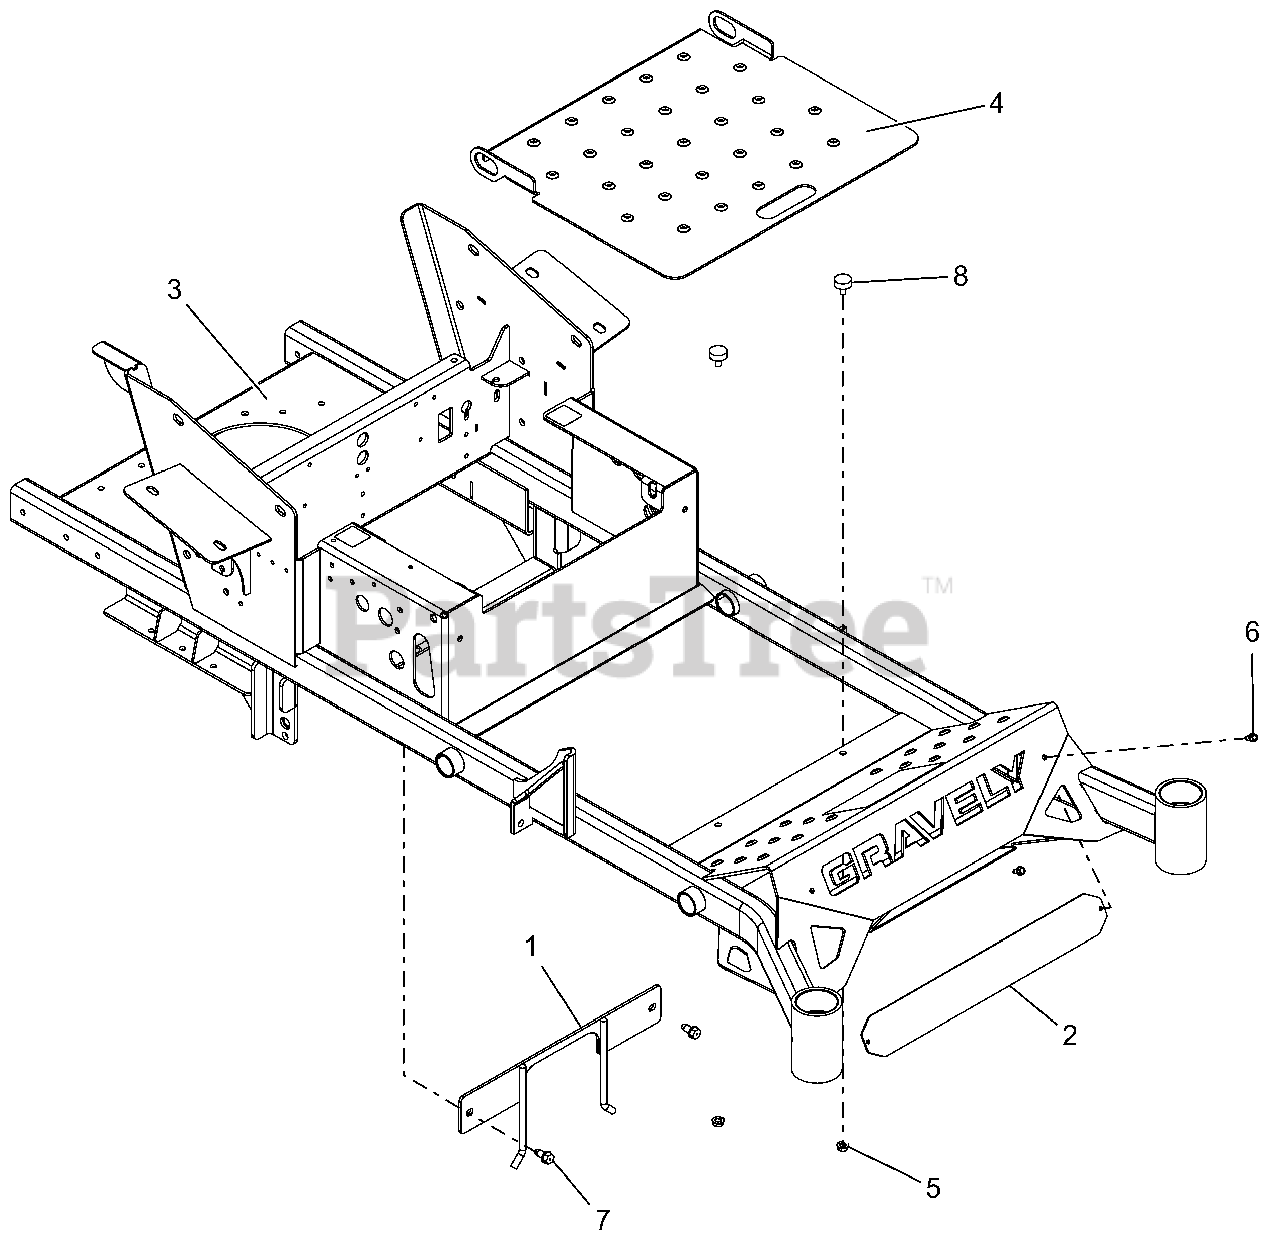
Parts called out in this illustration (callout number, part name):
1	PTO BELT FINGER WLDMT - BLK
2	BUMPER LOGO BACKING PLATE -BLK
3	PT/100 48-52 FRM W/SAFETY DECL
4	PT/100 FOOT PLT W/SAFETY DECAL
5	@NUT-SPNLK-FLG .312-18 YWZC
6	SCR-TAP .25-20X.50 HWH TR YWZ
7	@SCR-TAP .38-16X.75 HWH TR YWZ
8	BUMPER, RUBBER
